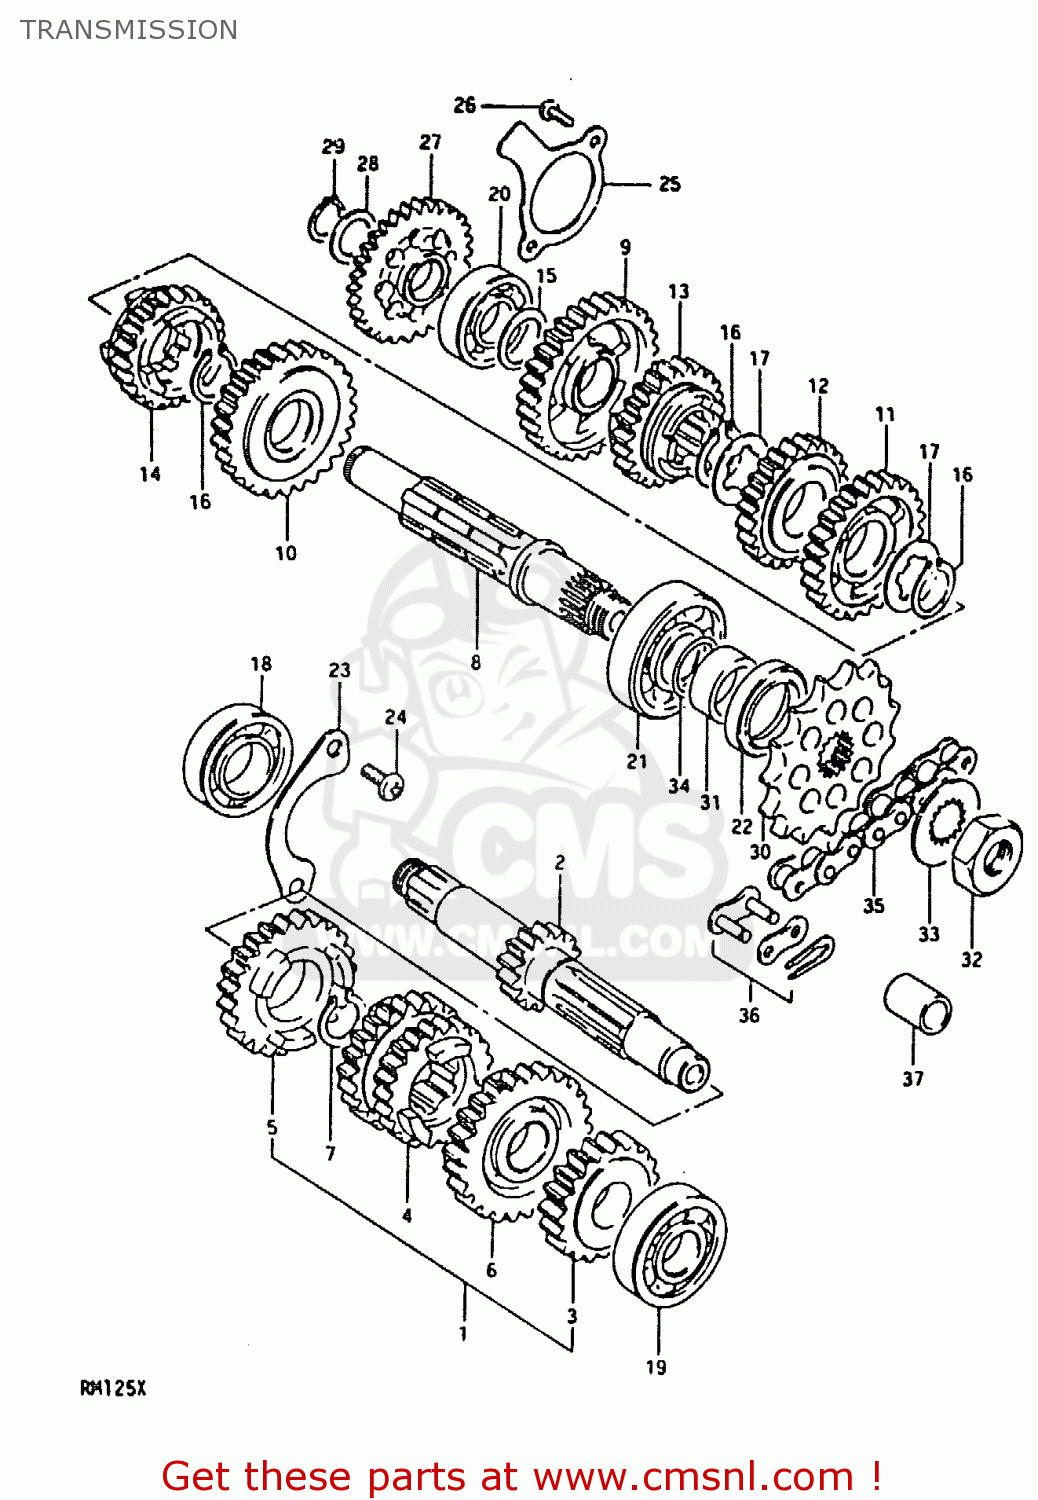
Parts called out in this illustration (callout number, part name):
1	SHAFT,COUNTER
2	SHAFT,COUNTER
3	GEAR,SECOND DRIVE
4	GEAR,THIRD/FOURTH DRIVE
5	GEAR,FIFTH DRIVE
6	GEAR,SIXTH DRIVE
7	CIRCLIP
8	SHAFT,DRIVE
9	GEAR, 1ST DRIVEN (NT:28)
10	GEAR,SECOND DRIVEN
11	GEAR,THIRD DRIVEN
12	GEAR,FOURTH DRIVEN
13	GEAR,FIFTH DRIVEN
14	GEAR,SIXTH DRIVEN
15	WASHER,THRUST
16	CIRCLIP
17	WASHER,LOCK
18	Bearing
19	BEARING
20	BEARING, RH
21	BEARING(20X47X14)
22	SEAL,OIL(25X40X7)
23	RETAINER,CNTR SHAFT BEARING
24	SCREW 6X12
25	RETAINER,DRIVESHAFT
26	SCREW 6X12
27	GEAR,KICK STARTER IDLE
28	WASHER,THRUST
29	CIRCLIP,15MM
30	SPROCKET,ENGINE
31	SPACER(20X25X12.5)
32	NUT
33	WASHER,LOCK
34	O RING(D:1,ID:19.5)
35	CHAIN ASSEMBLY,DRIVE
36	JOINT ASSEMBLY,CHAIN
37	CUSHION
